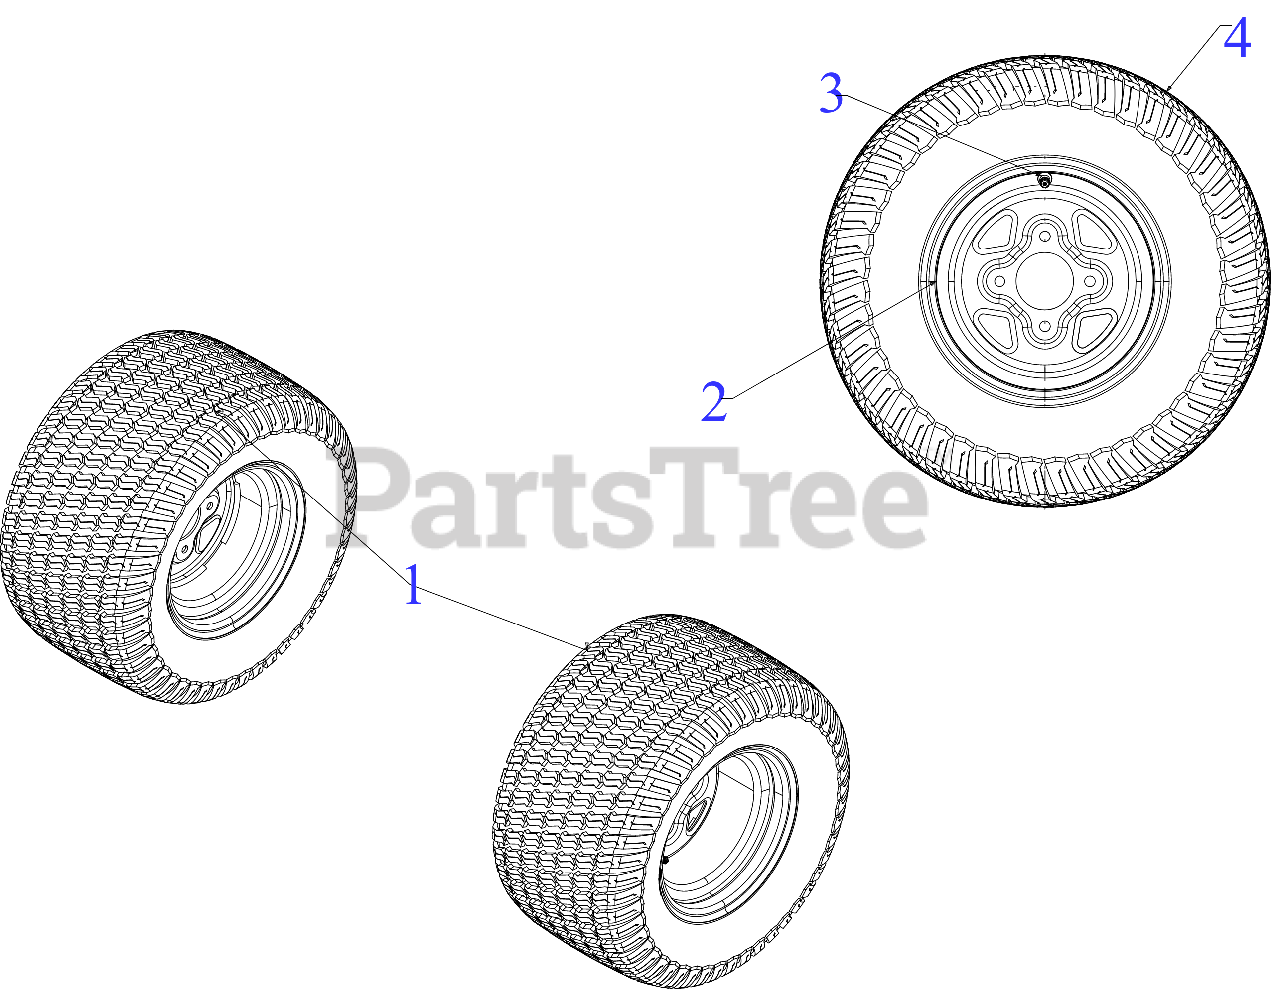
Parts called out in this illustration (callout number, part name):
1	COMPLETE WHEEL (20x12-10)(2PLY TM)
2	RIM
3	TUBELESS AIR VALVE
4	TIRE (20x12-10) TURFMASTR
